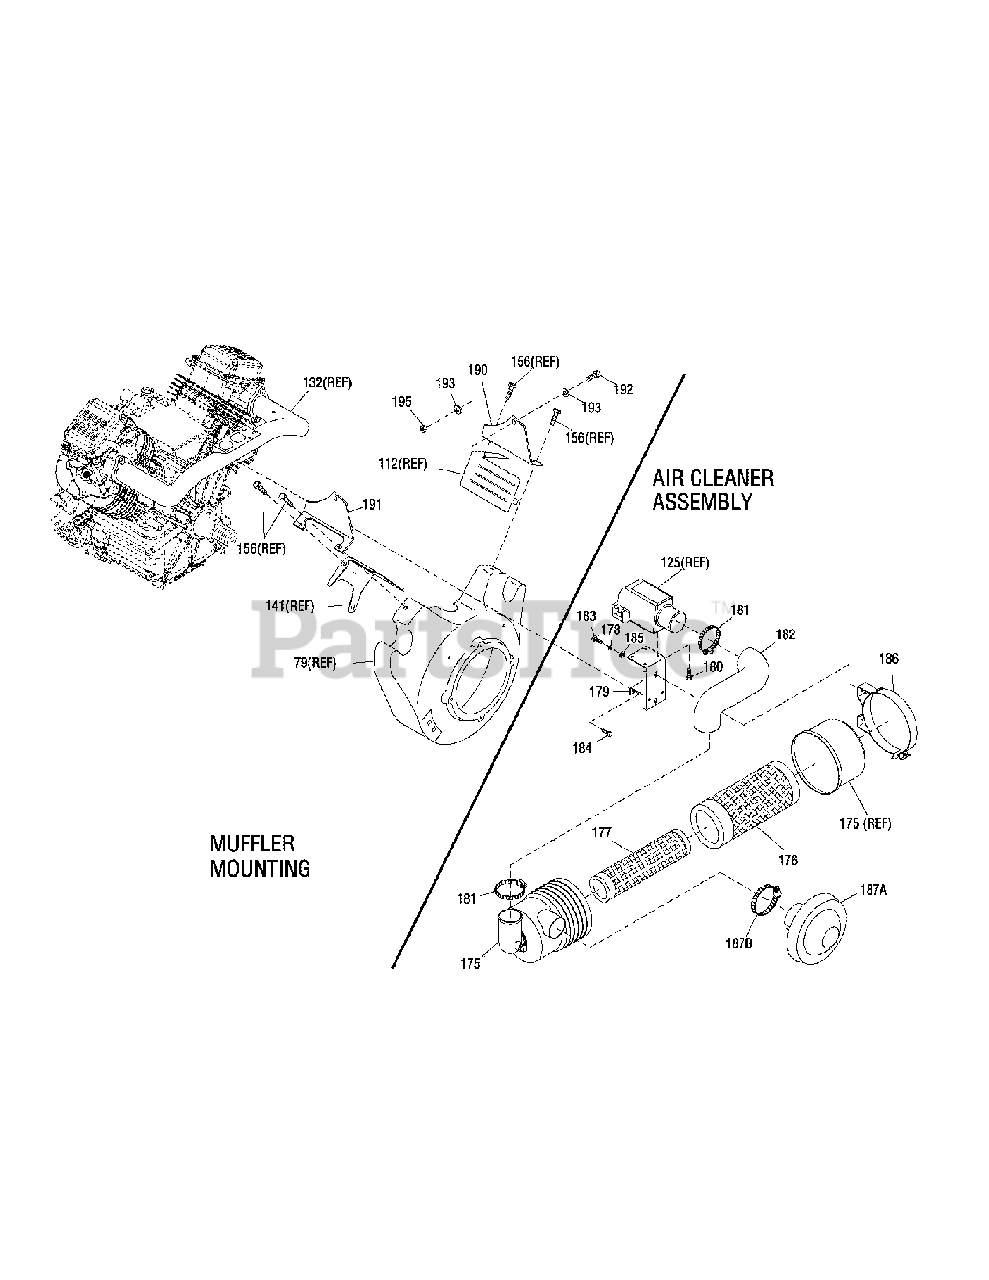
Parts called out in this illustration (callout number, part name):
79	HOUSING, BLOWER VERTICAL
92	PLATE, FAN
93	FAN, NYLON
112	WRAPPER, UPPER CYLINDER 1
125	ADAPTOR, CARB-AIRBOX, M6 BOSSES
132	MANIFOLD.INTAKE 2BBL CARB
141	WRAPPER, UPPER CYLINDER 2
156	SCREW, FHHC M6-1.0 x 12 W/M5 HEX
161	BRACKET, THROTTLE
175	CLEANER, AIR W/ SFTY FLT
176	FILTER, AIR PRIMARY
177	FILTER, AIR SAFETY (INNER)
178	WASHER LOCK M8-5/16
179	BRKT, AIR CLEANER SUPPORT
180	SCREW BHSC M6-1.0 x 12 SS
181	CLAMP HOSE #32 1.563-2.500
182	HOSE AIR CLEANER
183	SCREW HHC M8-1.25 x 16 G8.8
184	SCREW HHFC M6-1.0 x 10 G8.8
185	WASHER FLAT 5/16-M8 ZINC
186	ASSY, BAND MOUNT AIR CLEANER
187A	HOOD, INLET
187B	CLAMP, HOSE
190	NOT USED IN THIS APPLICATION
191	NOT USED IN THIS APPLICATION
193	NOT USED IN THIS APPLICATION
195	NOT USED IN THIS APPLICATION
